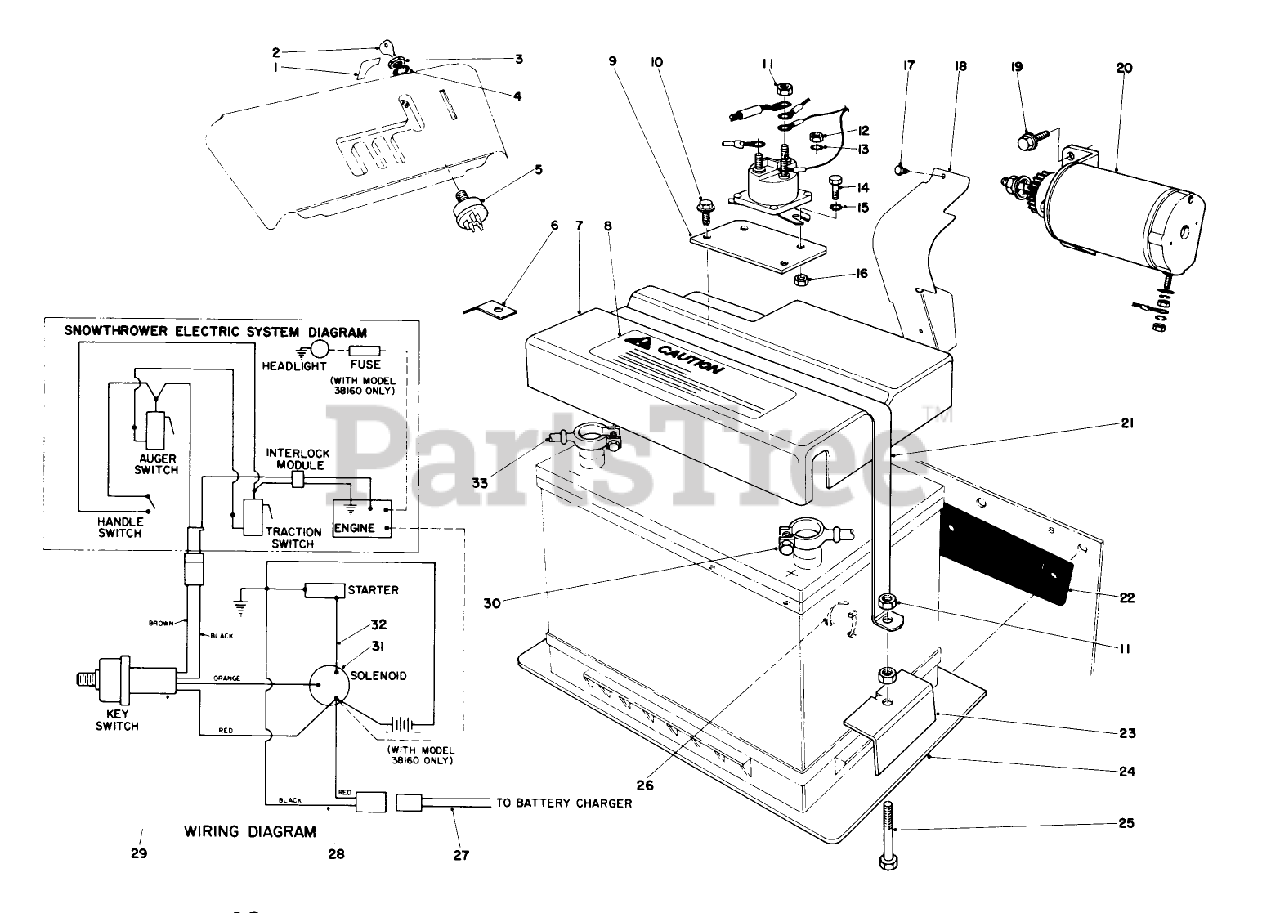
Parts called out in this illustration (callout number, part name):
3	NUT-HH
4	WASHER-LOCK
8	Decal-Caution
10	SCREW-HWH
11	NUT-HEX
12	NUT-HEX
13	WASHER-LOCK, INT
14	SCREW-HH
15	WASHER-LOCK/EXT
16	NUT-LOCK, NI
18	BRIGGS 280265
19	5/16-18X3/4 HX HD SEM
20	Starter Motor Pinion Assy.
25	SCREW-HH
26	TIE-CABLE
27	MALE WIRE ASM
30	BATT-SOLENOID CABLE
31	SOLENOID
